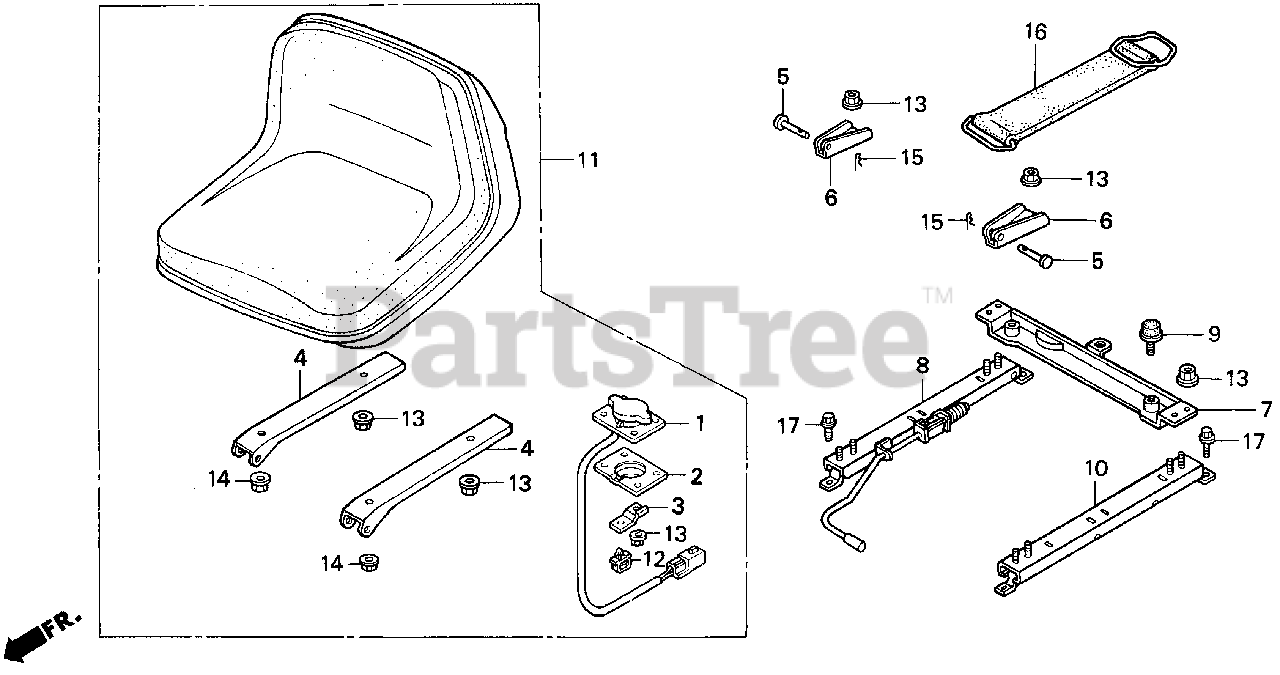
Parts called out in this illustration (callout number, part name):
1	SWITCH, SEAT
2	COVER, SEAT SWITCH
3	BASE, CLIP
4	BASE, SEAT (UPPER)
5	PIN, SEAT BASE (8MM)
6	HINGE, SEAT
7	CROSSMEMBER, SLIDE ADJUSTER
8	ADJUSTER, R. SLIDE
9	RUBBER, SEAT
10	ADJUSTER, L. SLIDE
11	SEAT ASSY.
12	CLIP, WIRE HARNESS (6MM) (WHITE)
13	NUT, FLANGE (6MM)
14	NUT-WASHER (6MM)
15	PIN, LOCK (8MM)
16	BAND C, BATTERY
17	BOLT, FLANGE (6X12)
